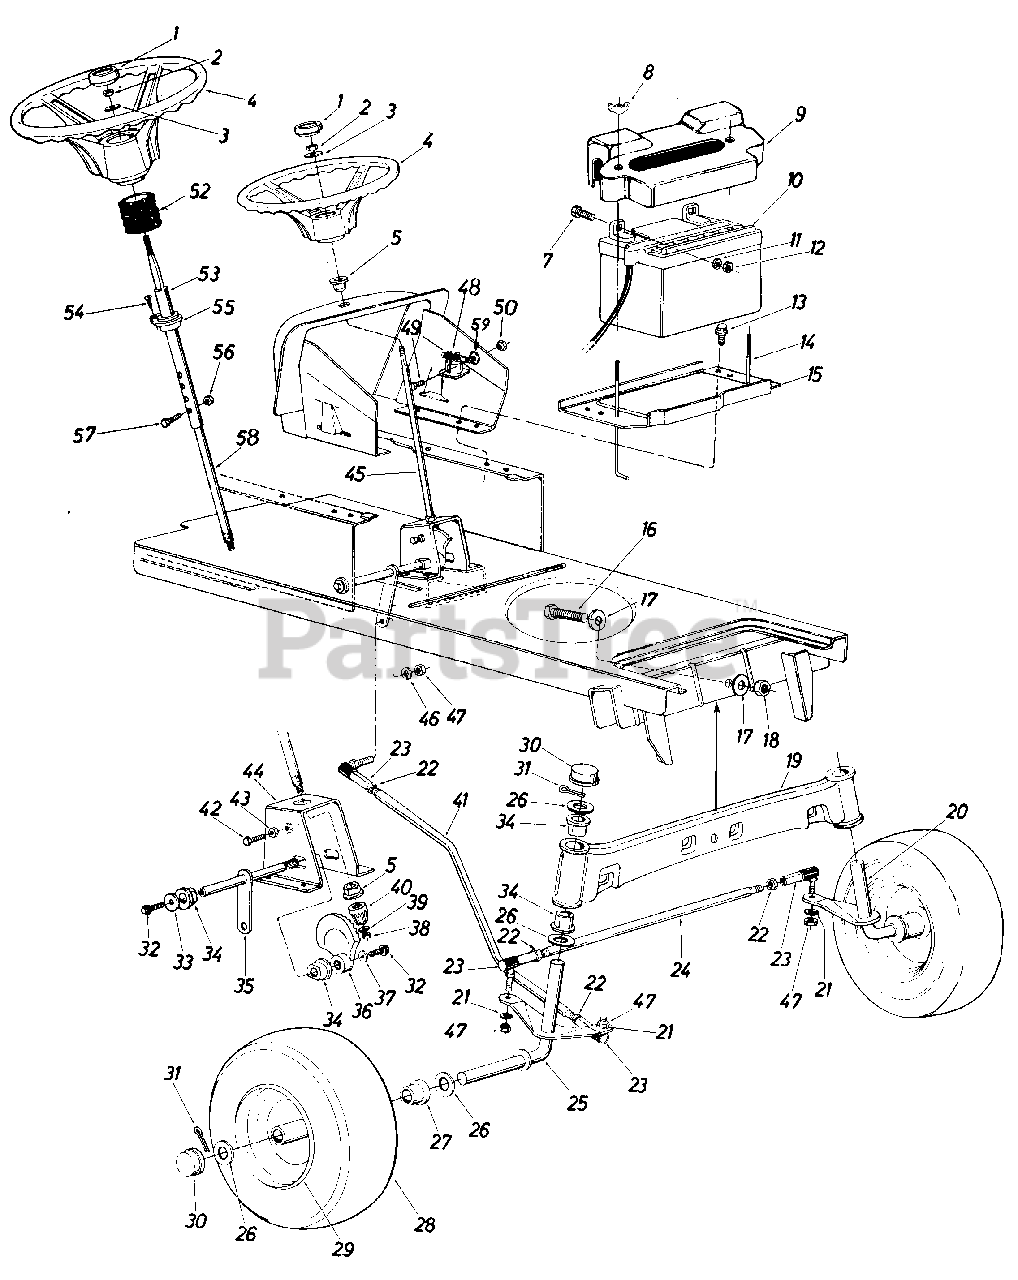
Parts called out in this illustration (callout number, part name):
1	Steering Wheel Cap
2	Hex Cent. L-Nut 5/16-24 Thd.
3	Bell-Wash. 5/16" I.D. x .87" O.D. x .060
4	Steering Wheel
5	Plastic Hex Bearing 5/8" I.D.
7	Hex Scr. 1/4-20 x .62" Lg.
8	Wing Nut Plastic 1/4-20 Thd.
9	Battery Cover
10	12-V Battery
11	L-Wash. 1/4" I.D.*
12	Hex Nut 1/4-20 Thd.
13	Hex Thd. Rolling Scr. 1/4-20 x.50" Lg.
14	Battery Hold Down Rod
15	Battery Plate
16	Hex Scr. 5/8-18 x 2.50" Lg.*
17	Flat Wash. .66" I.D. x 2.25" O.D. x .17
18	Hex Cent. L-Nut 5/8-18 Thd.
19	Front Pivot Bar Ass'y.
20	Front Axle Ass'y.-L.H.
21	L-Wash. 3/8" I.D.*
22	Hex Jam Nut 3/8-24 Thd.
23	Ball Joint Ass'y.
24	Tie Rod
25	Front Axle Ass'y.-R.H.
26	Fl-Wash. .780 I.D. x 1.59 O.D.
27	Flange Bearing
28	Front Wheel Ass'y. Comp.
29	Front Wheel Rim Only
30	Dust Cover
31	Cotter Pin 5/32" Dia. x 1.00" Lg.*
32	Hex Scr. 3/8-24 x .75" Lg. Grade 5
33	Fl-Wash. 3/8 I.D. x 1.25 O.D. x .090
34	Flange Double "D" Brg. .753 I.D.
35	Steering Arm Shaft Ass'y.
36	Side Gear-Steering
37	Bell-Wash. 3/8" I.D.
38	Hex Cent. L-Nut 5/16-24 Thd.
39	Fl-Wash. 5/16" I.D. x .62 O.D. x .059
40	Pinion Gear-Steering
41	Drag Link
42	Hex Nylon Scr. 3/8-16 x 1.25" Lg.
43	Hex Nut 3/8-16 Thd.
44	Steering Gear Sup. Ass'y.
45	Steering Shaft
46	L-Wash. 3/8" I.D.
47	Hex Nut 3/8-24 Thd.
48	Solenoid
49	Hex Bolt 1/4-20 x .50" Lg.
50	Hex Sems Nut 1/4-20 Thd.
52	Steering Bellow
53	Upper Steering Shaft
54	Oval Hd. Cr.-Sunk Scr. #10 x 518" Lg.
55	Fl-Bearing .89" I.D. x 1.36" O.D.
56	Hex L-Nut 1/4-20 Thd
57	Hex Bolt 1/4-20 x 1.31" Lg.
58	Lower Steering Shaft
59	External L-Wash. 1/4" I.D.
